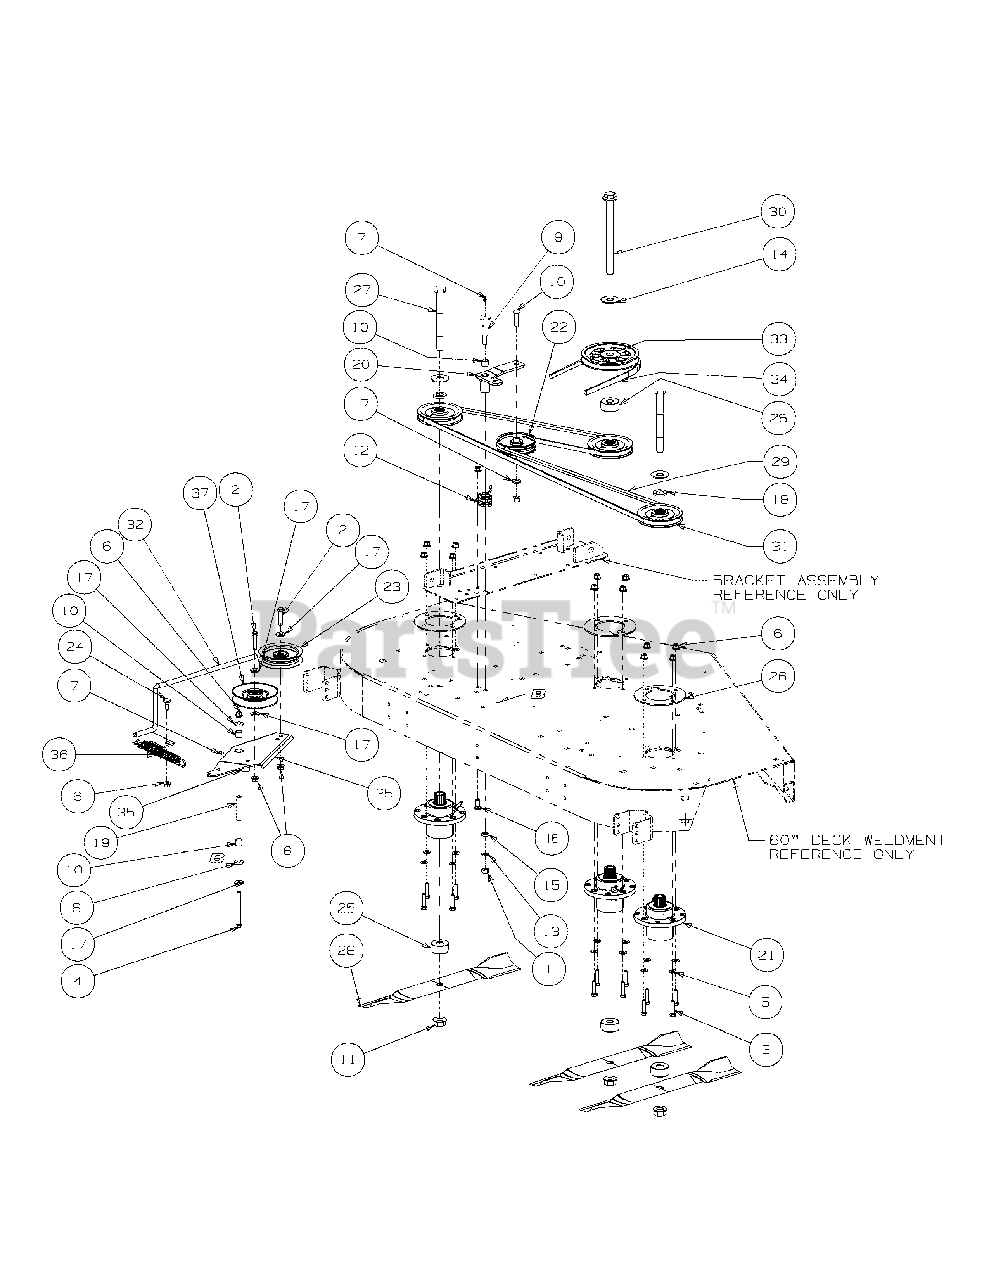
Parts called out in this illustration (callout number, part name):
1	Hex Nut, 7/16-14
2	Hex Cap Screw, 3/8-16 x 1-3/4
3	Hex Cap Screw, 3/8-16 x 1-1/2
4	Hex Cap Screw, 3/8-16, 4.00
5	Flat Washer, 3/8
6	Flange Lock Hex Nut, 3/8-16
7	Grease Fitting, 1/4-28 x 3/16
8	Idler Washer
9	Shoulder Screw, 7/16-14
10	Hex Carriage Screw, 3/8-16, 1.75
11	Flange Hex Nut, 3/4-16
12	Torsion Idler Spring
13	Lock Washer, 7/16
14	Flat Washer, .781 ID 2.00 OD, .105
15	Flat Washer, .469 ID, .875 OD, .105
16	Carriage Bolt, 3/8-16 x 1
17	Flat Washer, .406 ID, 1.0 OD, .105
18	Spacer .812 ID x .268 LG
19	Spacer, .39 ID x .625 OD x 2.75
20	Idler Arm Assembly, Deck Spindle includes
21	Aluminum Spindle Assembly
22	Flat Pulley
23	PULLEY-FLAT IDLER 4.875
24	Shoulder Screw, .50 x .27 Lg., 3/8-16
25	Spacer, .760 ID x 2.00 OD x 1.1
26	Aluminum Spindle Support Plate
27	Hex Cap Screw, 3/4-16, 7.00
28	Hi-Lift Blade, 21.0, 0.756 ID
29	V-Belt, A Section x 122.3
30	Hex Cap Screw, 3/4-16, 9.00
31	V-Pulley, 5.00 OD
32	Spring Tension Rod Assembly
33	V-Pulley, Cast, 6.360 OD
34	V-Belt, B Section x 147.4
35	Idler Arm Assembly Service Kit
36	Extension Spring, .94 x OD x 7.57
37	Idler Pulley, 5.06 Dia.
